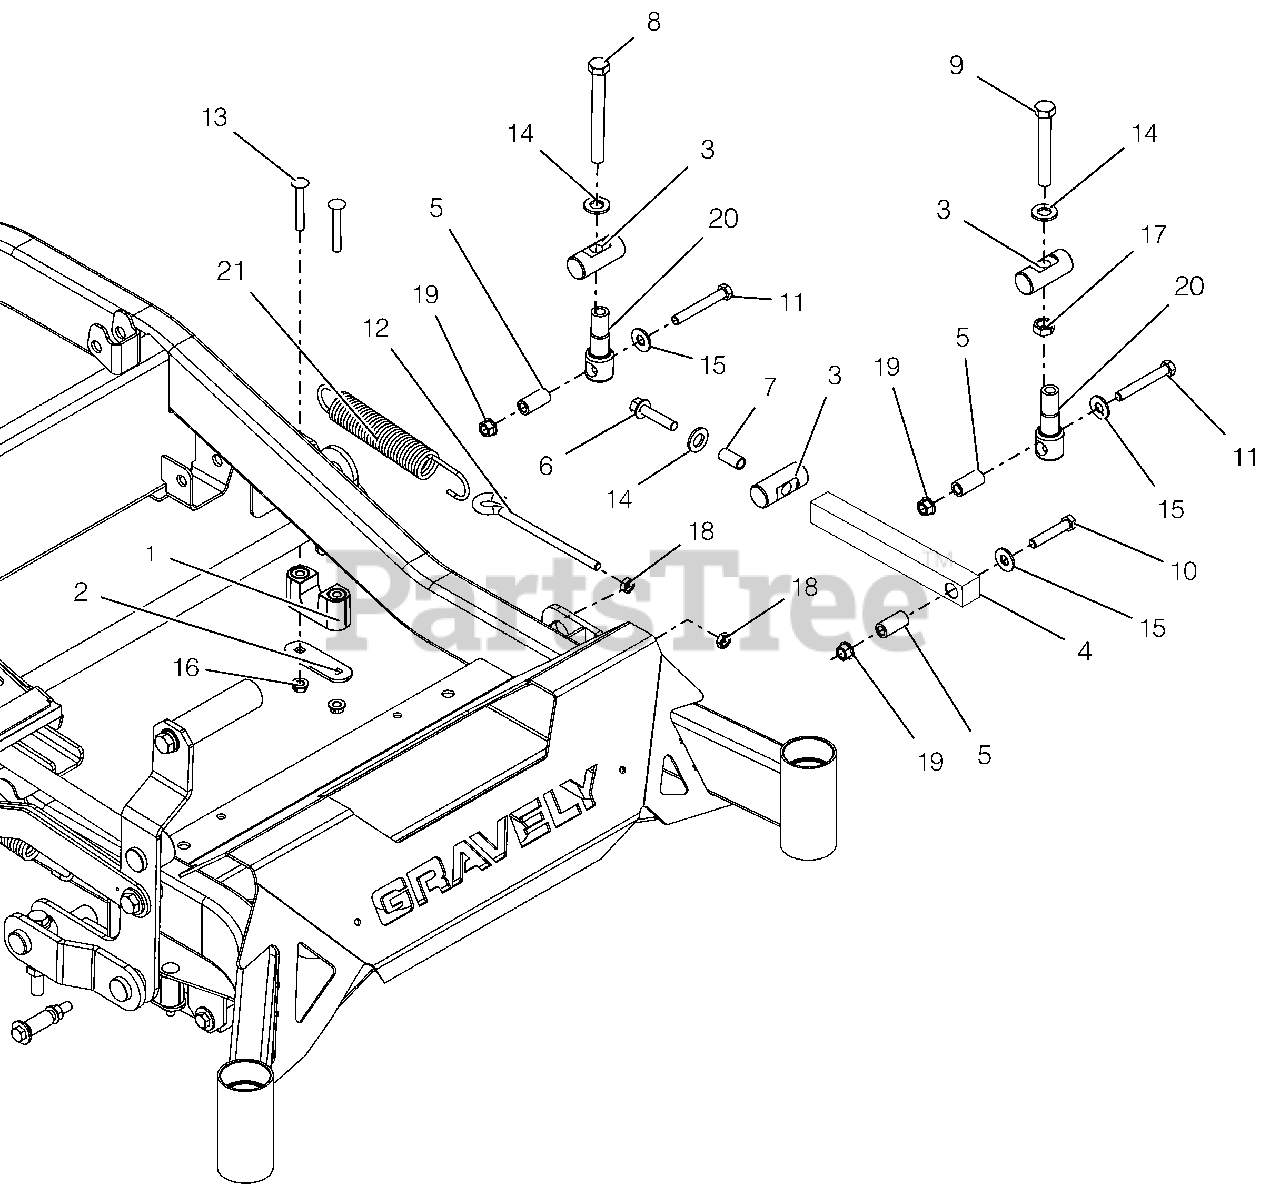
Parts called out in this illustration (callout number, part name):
1	ASM-BUSHING, DECK LIFT
2	PLATE, BEARING SUPPORT
3	PIN, DECK LIFT
4	LINK, DRAG
5	SPACER, DECK LEVELING
6	BLT,HEX-FLG .38-16X1.75 G5 ZCC
7	BSHG-SLV .385X.500X1.045
8	@BLT-HEX .5-13-4.5GR8 FULL THD
9	BLT-HEX .50-13X3.50 GR5 FTH
10	@BLT-HEX .38-16X2.00 GR5 YWZC
11	BLT-HEX .38-16X2.75 GR8 YWZC
12	BOLT,.38-16 X 5.25-.62 DIA EYE
13	BLT-RDHDSQSHNK .31-18X2.25 YWZ
14	FLATWASHER 1/2 SAE HARD 15906
15	@WSHR-FL-STL.438X1.00X.083 YWZ
16	@NUT-LK-CTR-FLG .31-18 YZ GR F
17	NUT-JAM .50-13 YWZC
18	NUT-HEX-JAM .375-16 YWZC
19	@NUT-LK-TOP-FLG .38-16 YWZC
20	LINK, DECK LIFT FORMED
21	SG-TENS .162X1.25X8.25 WLD 25
